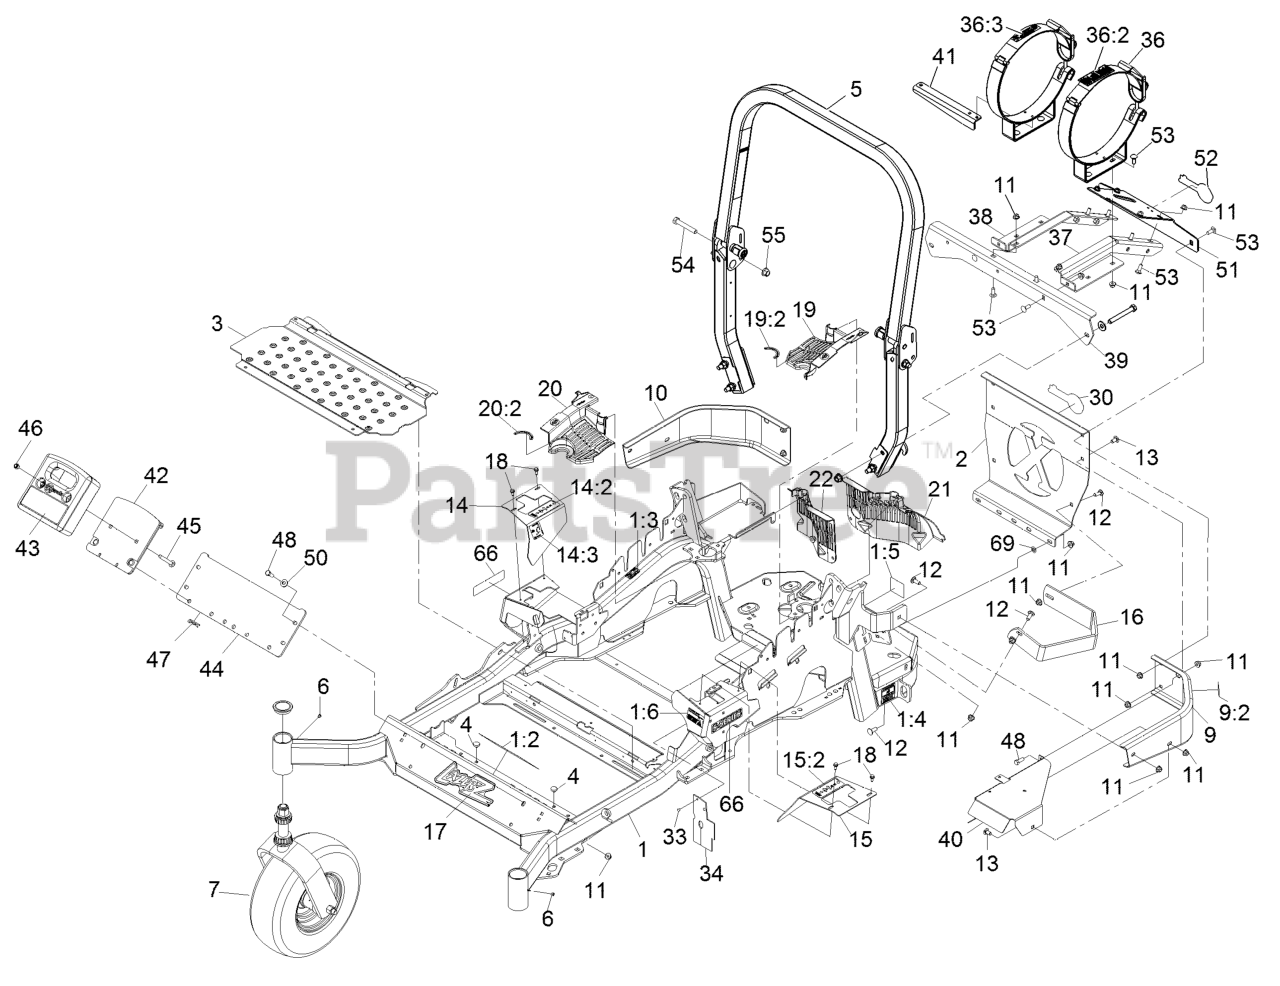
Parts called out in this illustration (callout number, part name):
1	MAINFRAME ASM
1:2	DECAL-SLOPE
1:3	DECAL-CAUTION
1:4	DECAL-BELT DRIVE
1:5	DECAL-SPARK ARRESTER
1:6	DECAL-FUEL FILL
2	PLATE,REAR GUARD
5	ROPS ASM
7	Asm,Front Caster W/Fork
9	LH BUMPER ASM
9:2	DECAL-CAUTION
10	BUMPER-RH
11	NUT-HF, NI
12	SCREW-CARR
13	SCREW-CARR
14	RH MOTION CONTROL COVER ASM
14:2	DECAL-MOTION CONTROL
14:3	DECAL-PARK BRAKE
15	LH MOTION CONTROL COVER ASM
15:2	DECAL-MOTION CONTROL
17	DECAL,LAZER MODEL
18	SCREW-HWH
19	LH HYDRO GUARD ASM
19:2	DECAL-HYDRO OIL
20	RH HYDRO GUARD ASM
20:2	DECAL-HYDRO OIL
21	GUARD-HYDRO, REAR (LH)
22	GUARD-HYDRO, REAR (RH)
33	RIVET-POP
34	DEFLECTOR-AIR FLOW
36	TANK BRACKET ASM (SET)
36:2	DECAL-LPG WARNING
36:3	DECAL-LPG 43.5LB TANK
37	LH LPG FRAME ASM
38	RH LPG FRAME ASM
39	SUPPORT-LPG FRAME, FRONT
40	PANEL-LPG, AC
41	PLATE-INDEX, LPG TANK
42	WLD,WEIGHT MOUNT
43	WEIGHT,CAST 36LB
44	PLATE,WEIGHT ASM MOUNT
45	SCREW-CARR
46	NUT-LOCK, NI
47	PIN-HAIR
48	SCREW-HH
50	WASHER-BELLEVILLE
51	SUPPORT-REAR FRAME, LPG
53	BOLT-CARR
54	SCREW-HH
55	Nut-Lock 1/2-13
66	DECAL-S-SERIES
69	NUT-PUSH
